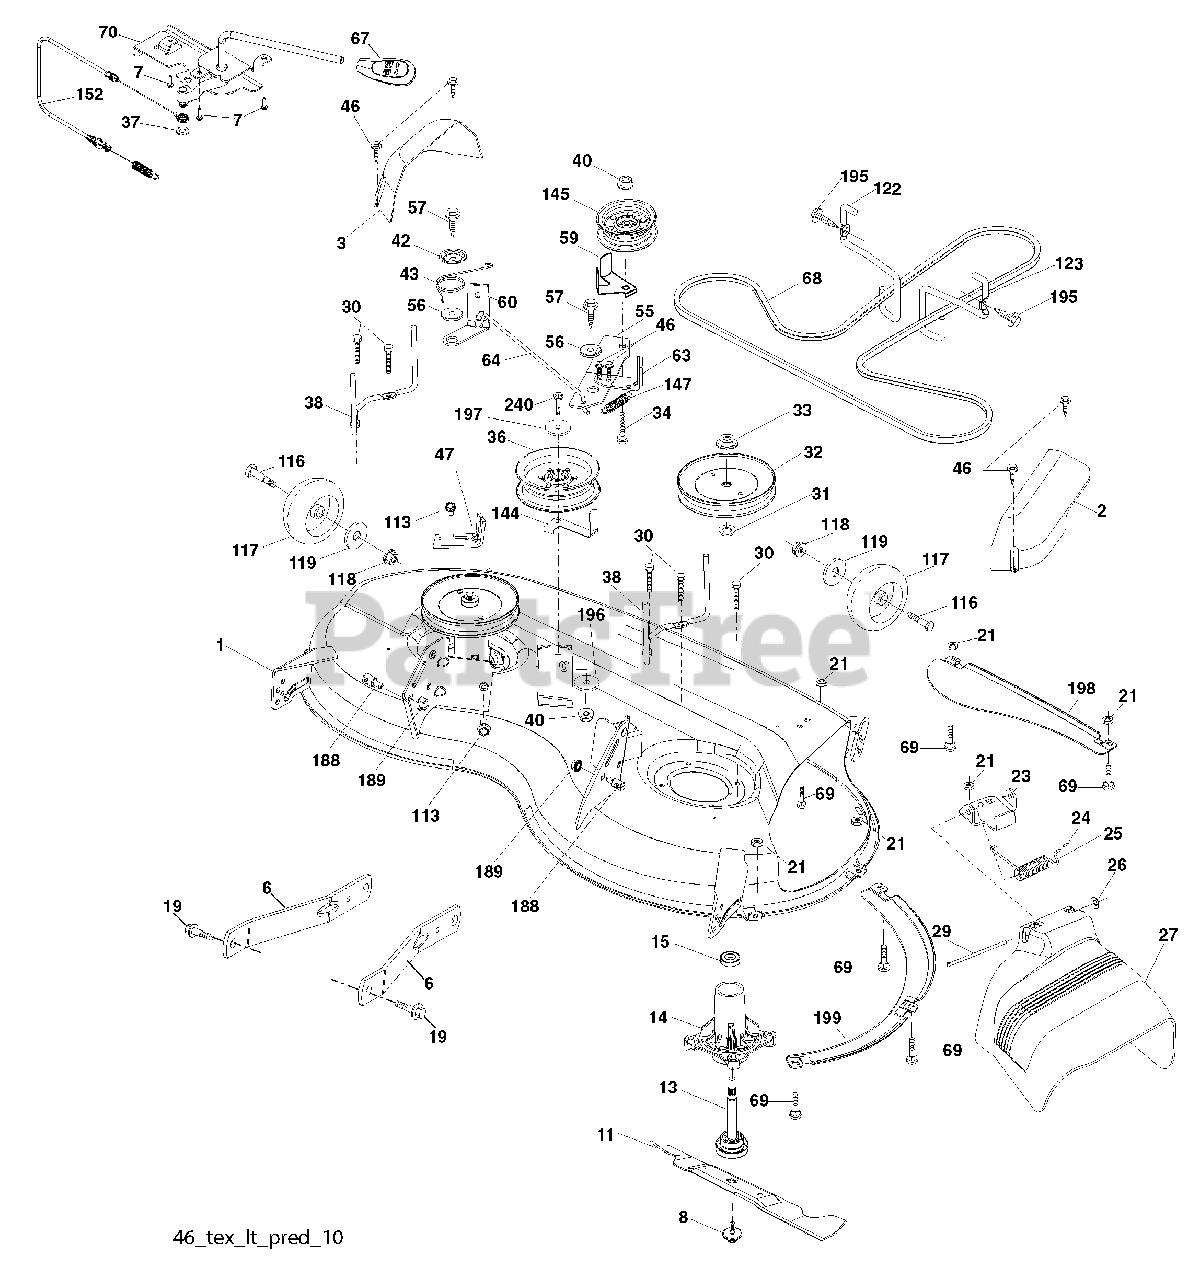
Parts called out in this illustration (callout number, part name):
2	Cover Mandrel RH
3	Cover Mandrel LH
5	Retainer Spring
6	Arm Suspension
7	Screw 10 x 3/4 Single Hex
8	Bolt/Washer Asm 7/16-20 unf
11	Blade Mower
13	Shaft Assembly, Mandrel
14	Housing, Mandrel
15	Bearing, Ball, Mandrel
19	Bolt, Shoulder
21	Nut
23	Bracket, Deflector
24	Cap, Sleeve
25	Spring, Torsion, Deflector
26	Nut, Push
27	Shield, Deflector
29	Rod, Hinge
30	Screw Thdrol Rolling Wsh Hd
31	Washer, Spacer
32	Pulley, Mandrel
33	Nut, Toplock, Flanged
34	Bolt Carr Sh. 3/8-16 x 1-1/2 Gr. 5
36	Pulley, Idler
37	Washer 13/32 x 13/16 x 16 Ga.
38	Keeper Belt LH Mandrel
40	Nut, Lock Flg. 3/8-16 unc
42	Spring Torsion Brake
43	Spring Torsion Retainer
46	Screw
47	Bracket Clutch Cable
55	Arm, Idler
56	Spacer, Retainer
57	Screw Hexwsh Thd 3/8-16 x 1
59	Guard, Tuv Idler (94)
60	Arm Brake Mower
63	Arm Brake Mower
64	Linkage Brake
67	Handle, Clutch Cable
68	V-Belt
69	Bolt
70	Clutch Asm. Manual
113	Screw 5/16-18
116	Bolt, Shoulder
117	Wheel, Gauge
118	Nut, Crownlock 3/8-1
119	Washer 13/32 x 7/8 x 14 Ga.
122	Keeper Belt Eng. LH
123	Keeper Belt Eng. RH
144	Keeper Belt
145	Pulley Idler
147	Spring Return
152	Cable Clutch Manual w/Spr.
188	Stud Fastener
189	Nut Lock Hex Flange
195	Screw 3/8-16 x 3/4
197	Washer 13/32 x 13/16 x 12 Ga.
198	Baffle Center Front
199	Baffle Front RH
240	Bolt Fin Hex 3/8-16 x 2-1/4 Gr. 5
241	Washer 13/32 x 1 x 1/2 11 Ga.
241	Mandrel Assembly
241	Replacement Mower, Complete
